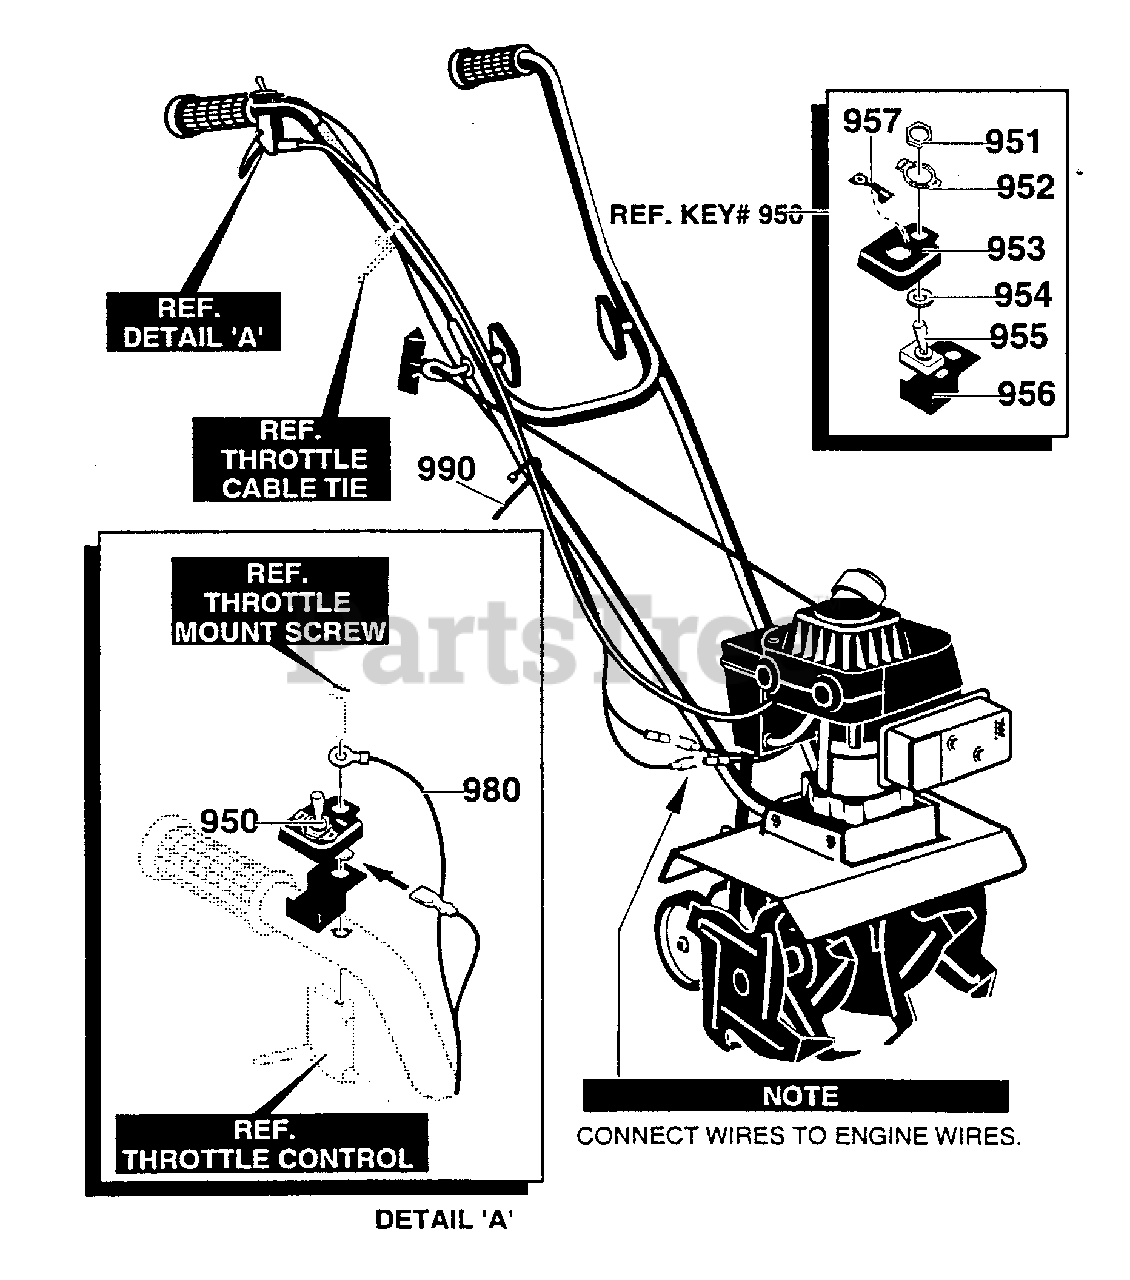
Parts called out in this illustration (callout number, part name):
950	SWITCH ASSEMBLY
951	PLATE, INDICATOR
953	BRACKET, SWITCH
954	LOCKWASHER
956	BRACKET, SWITCH
957	DECAL, ON-OFF
980	KILL SWITCH ASSEMBLY
